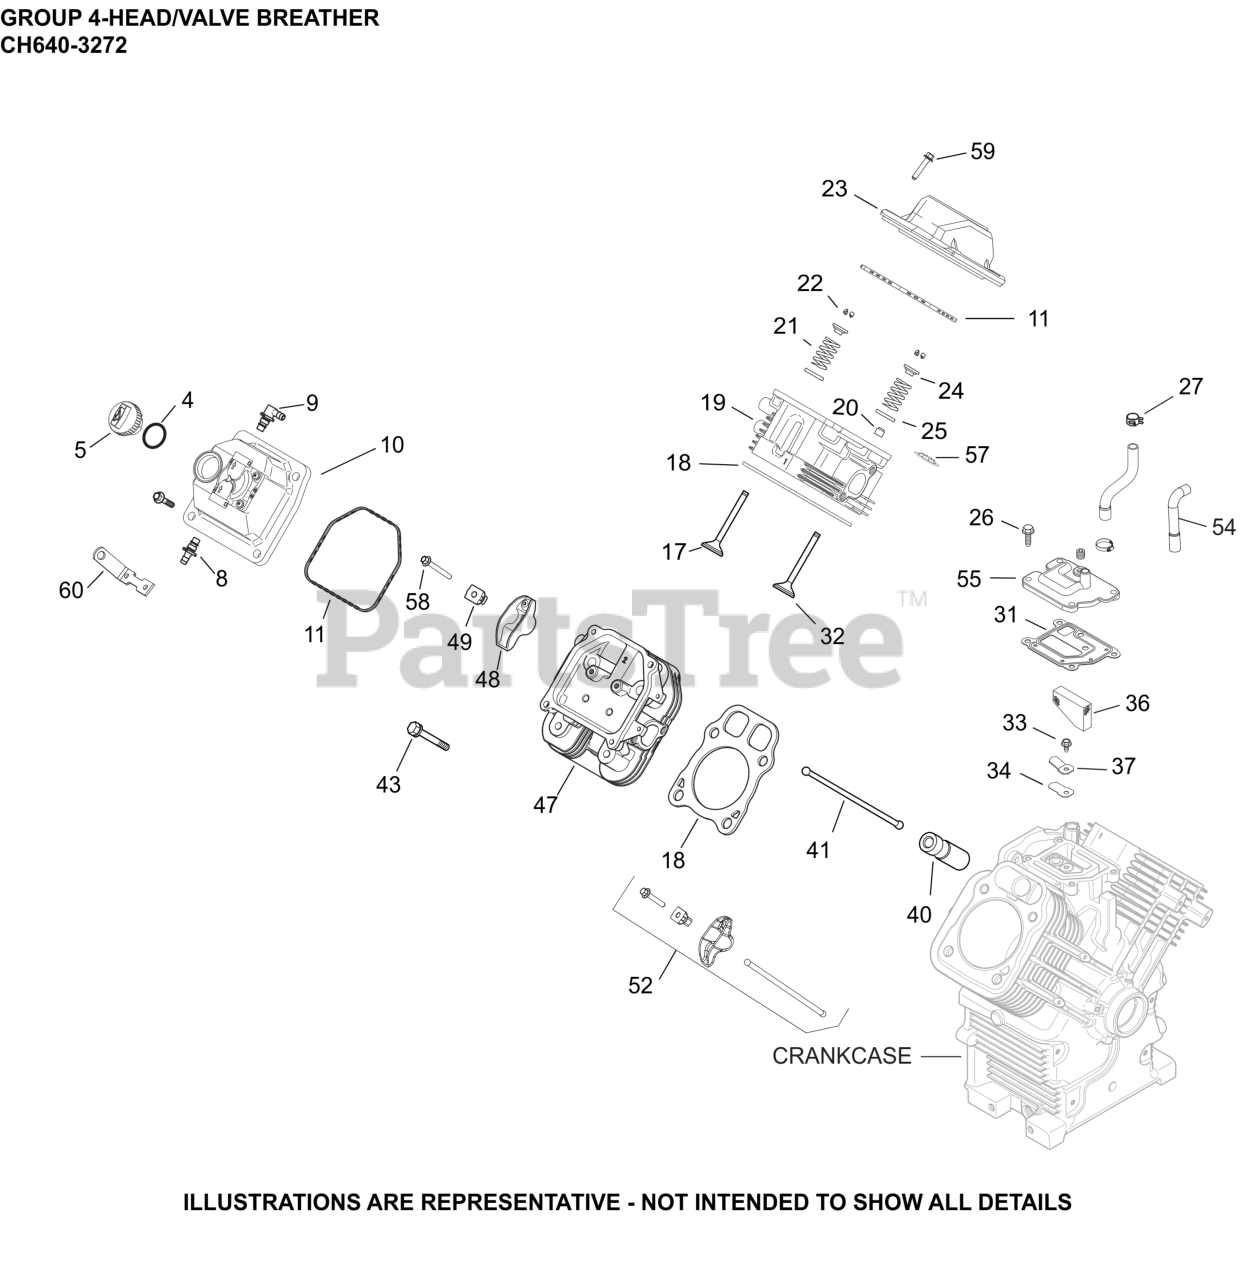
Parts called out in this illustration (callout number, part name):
5	CAP ASSY, OIL FILL (YELLOW)
8	KIT, STRAIGHT FITTING
9	KIT, 90 DEG. FITTING
10	KIT,VALVE COVER-FUEL PUMP
11	O-RING (YELLOW), VALVE CO
17	VALVE, EXHAUST
17	VALVE, EXHAUST (.25)
18	KIT, GSKT CYL HD (C22-23 674CC)
19	KIT, CYLINDER HEAD (#1)-(#2481803S)
20	SEAL, VALVE BAND
21	SPRING, VALVE
22	KIT, RETAINER
23	KIT, VALVE COVER-PLAIN (PLASTIC)
24	CAP, VALVE SPRING
25	RETAINER, SPRING
26	SCREW, THREAD FORMING
27	SPRING CLAMP, HOSE
31	GASKET, BREATHER
32	VALVE, INTAKE (STD)
32	VALVE, INTAKE (.25)-(#DSC)
33	SCREW, FLG THD FRM M5X.8X10
34	REED, BREATHER
36	FILTER, BREATHER
37	RETAINER, REED
40	LIFTER, VALVE HYDRAULIC-USE 25 351 11-S
41	ROD, PUSH
43	SCREW, FLG M10X1.5X90
47	KIT, CYLINDER HEAD (#2)-(#2481804S)
48	ARM, ROCKER
49	PIVOT, ROCKER ARM
52	KIT, VALVE TRAIN
54	HOSE, BREATHER
55	COVER, BREATHER
57	RETAINER, VALVE GUIDE (KM)
58	SCREW, HEX FLANGE
59	SCREW, HEX FLANGE (M6 X 31.625 DOG PT)
60	STRAP, LIFTING
